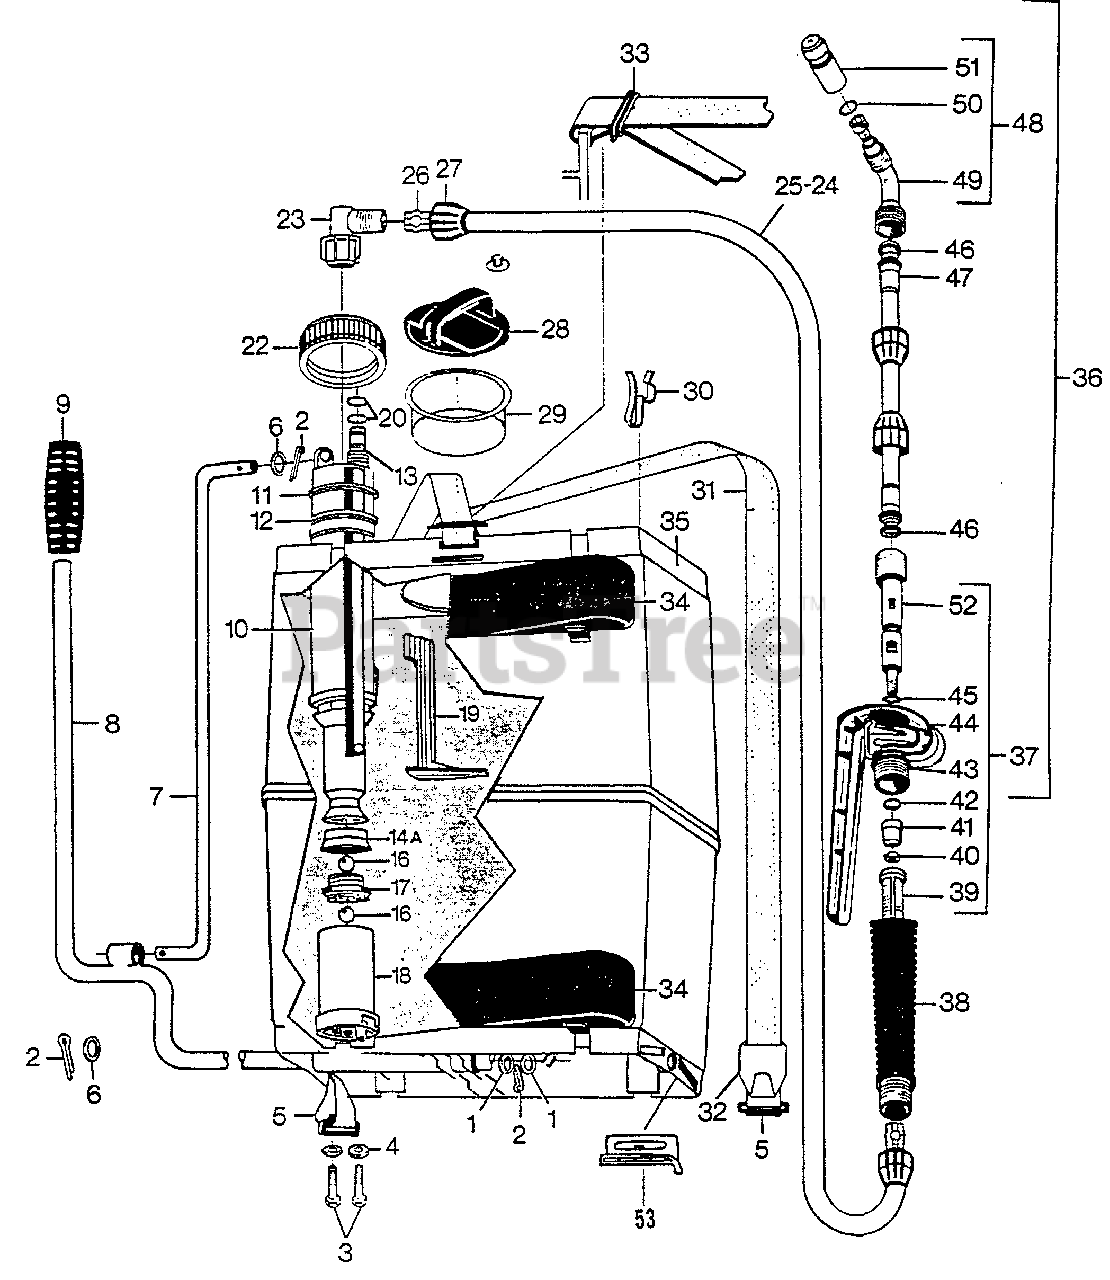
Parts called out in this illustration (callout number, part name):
1	WASHER, FLAT - 13×2
2	PIN - COTTER
3	SCREW - 8×25
4	WASHER -- PLATED
5	RING, STRAP
6	WASHER
7	ARM
8	LEVER, PUMP
9	GRIP
10	PUMP ASSY
11	WASHER, SEAL
12	BUSHING, GUIDE
13	PIPE ASSY
14	WASHER - RUBBER
14A	WASHER, CUP VITON
16	BEARING, BALL
17	VALVE
18	CYLINDER
19	AGITATOR
20	O-RING AN-6
20A	O-RING - 6
22	NUT, GUIDE
23	ELBOW
24	HOSE ASSY
25	HOSE - 60×12×1, 3M
26	HOSE CAP
29	FILTER, TANK
31	STRAP-1 - 9M
32	HOOK, STRAP END
33	RING, STRAP TIGHTENER
34	CUSHION, BACKPACK
35	TANK
36	WAND ASSY
37	HANDLE ASSY
38	HOLDER, FILTER
39	FILTER, WAND
42	O-RING AN 8
42A	O-RING - 8
43	O-RING
44	BODY, HANDLE
45	O-RING AN-6
45A	O-RING - 6
46	WASHER
47	PIPE ASSY
48	NOZZLE ASSY
49	SPRAYER
50	O-RING AN 5
50A	O-RING - 5
51	NOZZLE - 1 MM
51A	NOZZLE, 0.75 MM
51B	NOZZLE - 1.5 MM
52	HANDLE ASSY
